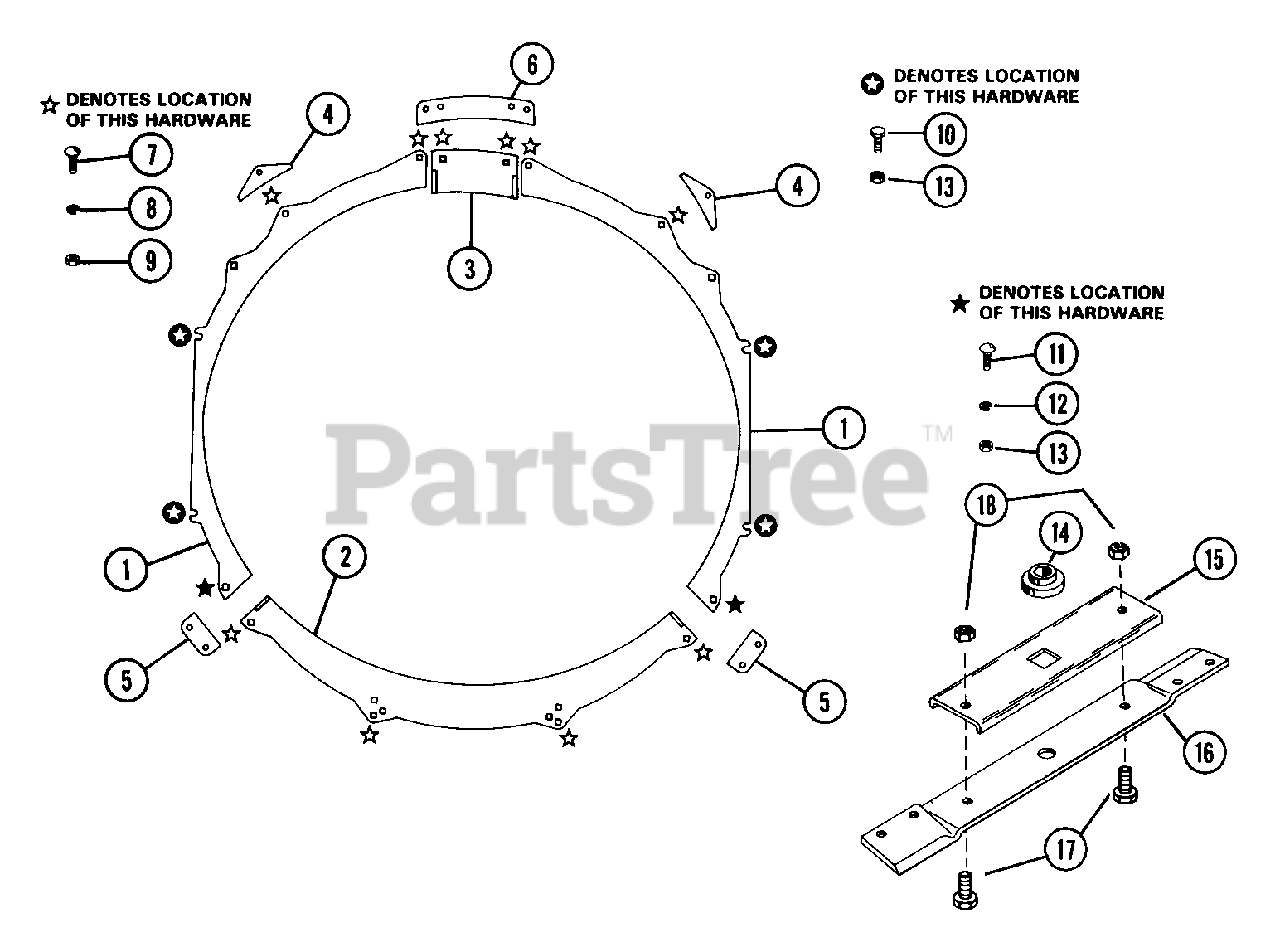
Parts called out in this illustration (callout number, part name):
1	SIDE FLANGE
2	BACK FLANGE
3	FRONT CLAMP
4	SIDE CLAMP
5	JOINT CLAMP
6	FRONT CLAMP
7	BLT-RDHDSQNK .25-20X.62 PL
8	WSHR-LK .313X.093 MED HICLR
9	NUT-LK-CTR .250-20 PL
10	BLT-HEX .31-18X.63 PL GR 2
11	BLT-RDHDSQNK .312-18X.62SHTPL
12	WSHR-LK .375X.115 HVY PL
13	NUT-LK .312-18 GR A PL
14	RETAINER HUB
16	MOWER BLADE 32
17	BLT-HEX .38-16X.75 PL GR5
18	NUT-LK TOP .375-16 GR C YWZC
